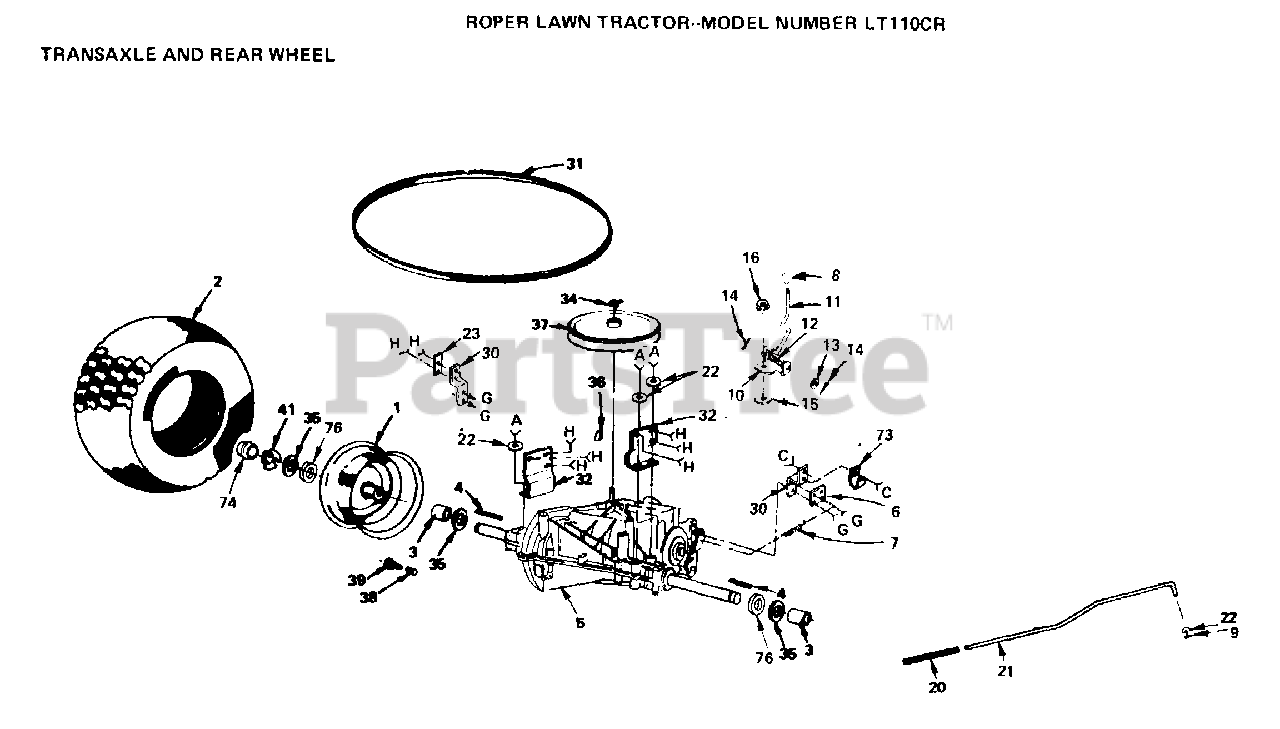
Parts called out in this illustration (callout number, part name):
3	WHEEL SPACER LT
6	BRACKET-SPRING LT
7	SPRING-EXT LT
8	KNOB T (1/2-HOLE)
9	COTTER PIN
10	PLATE SHIFT LT
12	SPRING LT
13	WASHER
14	PIN COTTER 1/8
15	WASH-SHFT PLT LT
21	ROD BRAKE LT
22	WASHER
23	PLATE-STRAP LT
30	"STRAP, TORQUE LT"
38	VALVE CAP
39	VALVE STEM LT
41	E-RING LT
73	INSUL CLIP T
74	HUB CAP
75	SPRING T
76	WASHER LT
